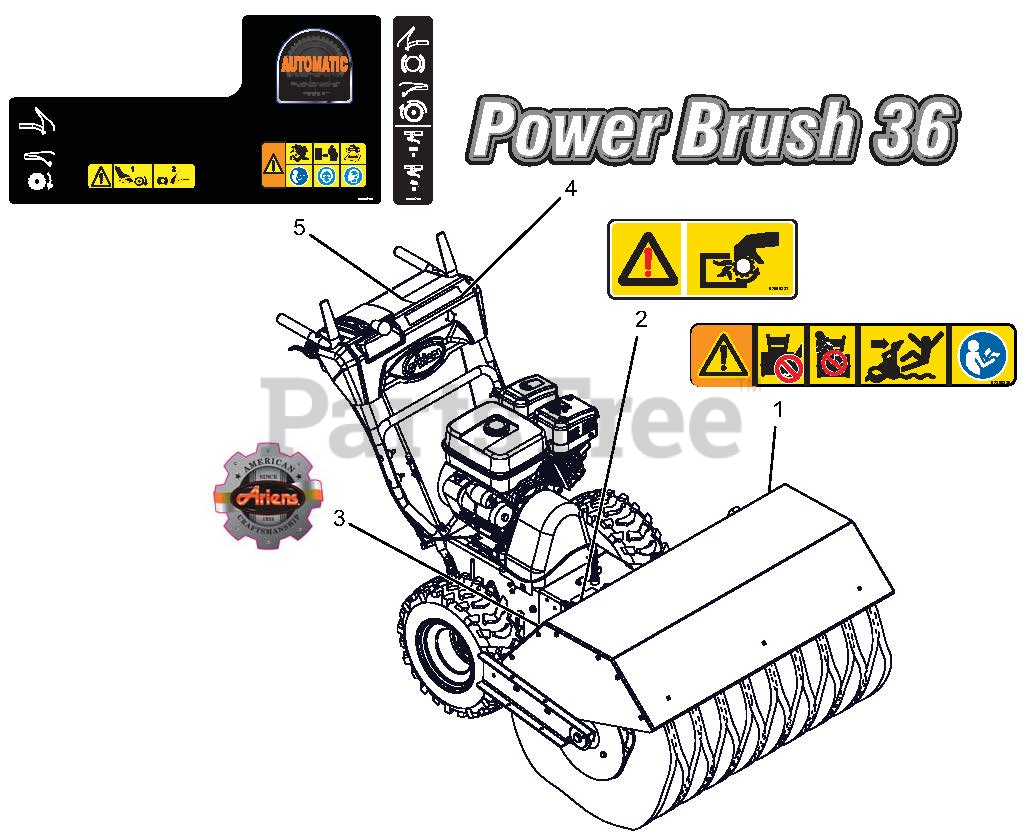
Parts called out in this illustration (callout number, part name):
1	DECAL, DANGER -POWER BRUSH-CE
2	DECAL, PTO WARNING
3	DECAL, ARIENS HERITAGE-LARGE
4	DECAL,POWER BRUSH 36",ARIENS
5	DECAL, CONTROL, LARGE BRUSH
